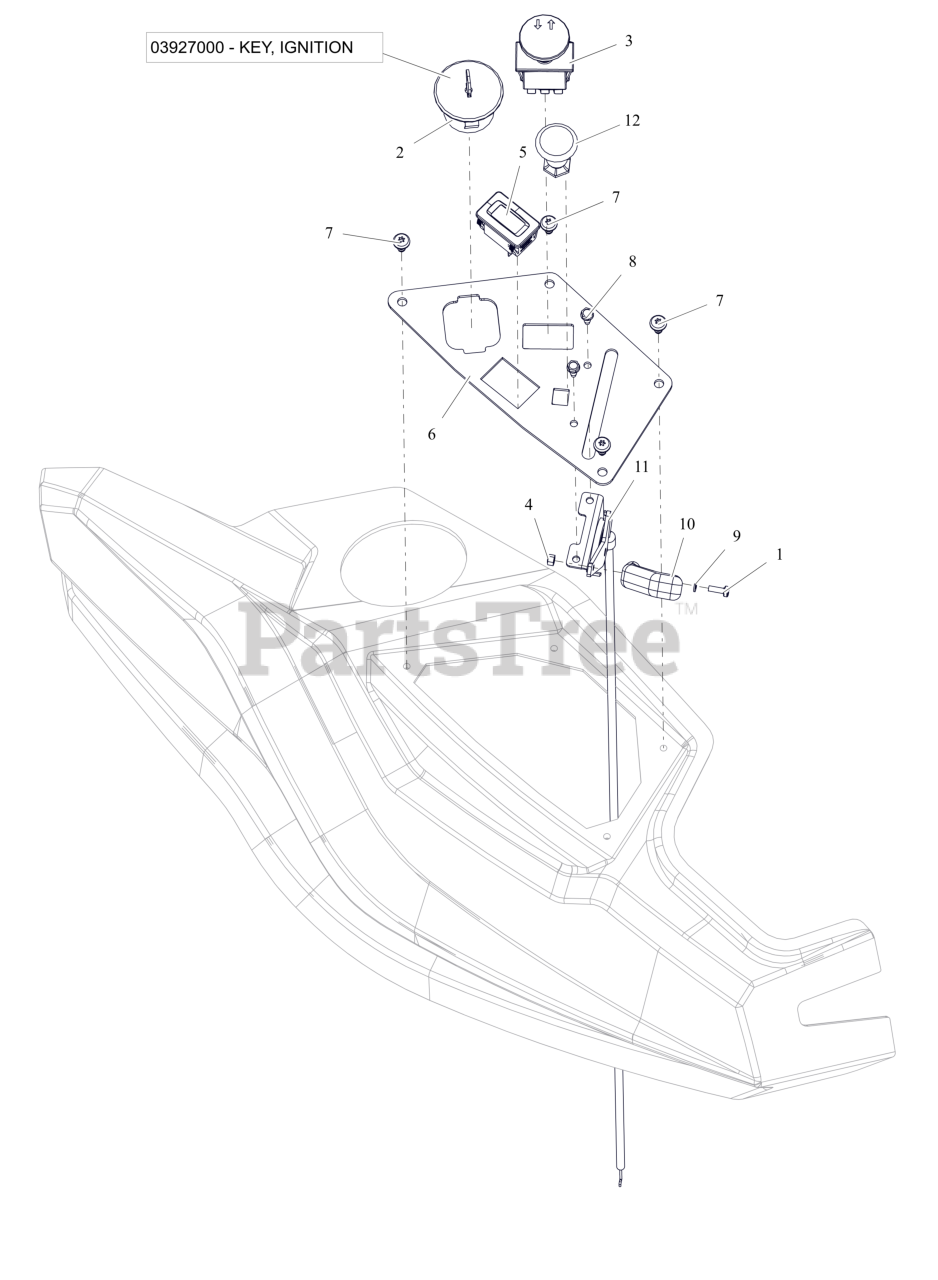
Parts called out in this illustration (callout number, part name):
1	M4 X 12 POZI PAN MACHINE SCREW
2	KEYSWITCH-IGNITION 3 POS
2	KEY, 03290500 KEYSWITCH
3	SWITCH, CLUTCH (YELLOW)
4	NUT, NYLOC M4
5	HOUR METER
6	PANEL, CONTROL (ORANGE)
7	SCR-PAN .25-15X.50 6L H/LZB500
8	SCR,TAP #10-24X.50 HWH TR ZCC
9	CAP,TANK
10	KNOB, CONTROL
11	THROTTLE, LONCIN LC2P76F 635CC
12	CABLE, CHOKE
